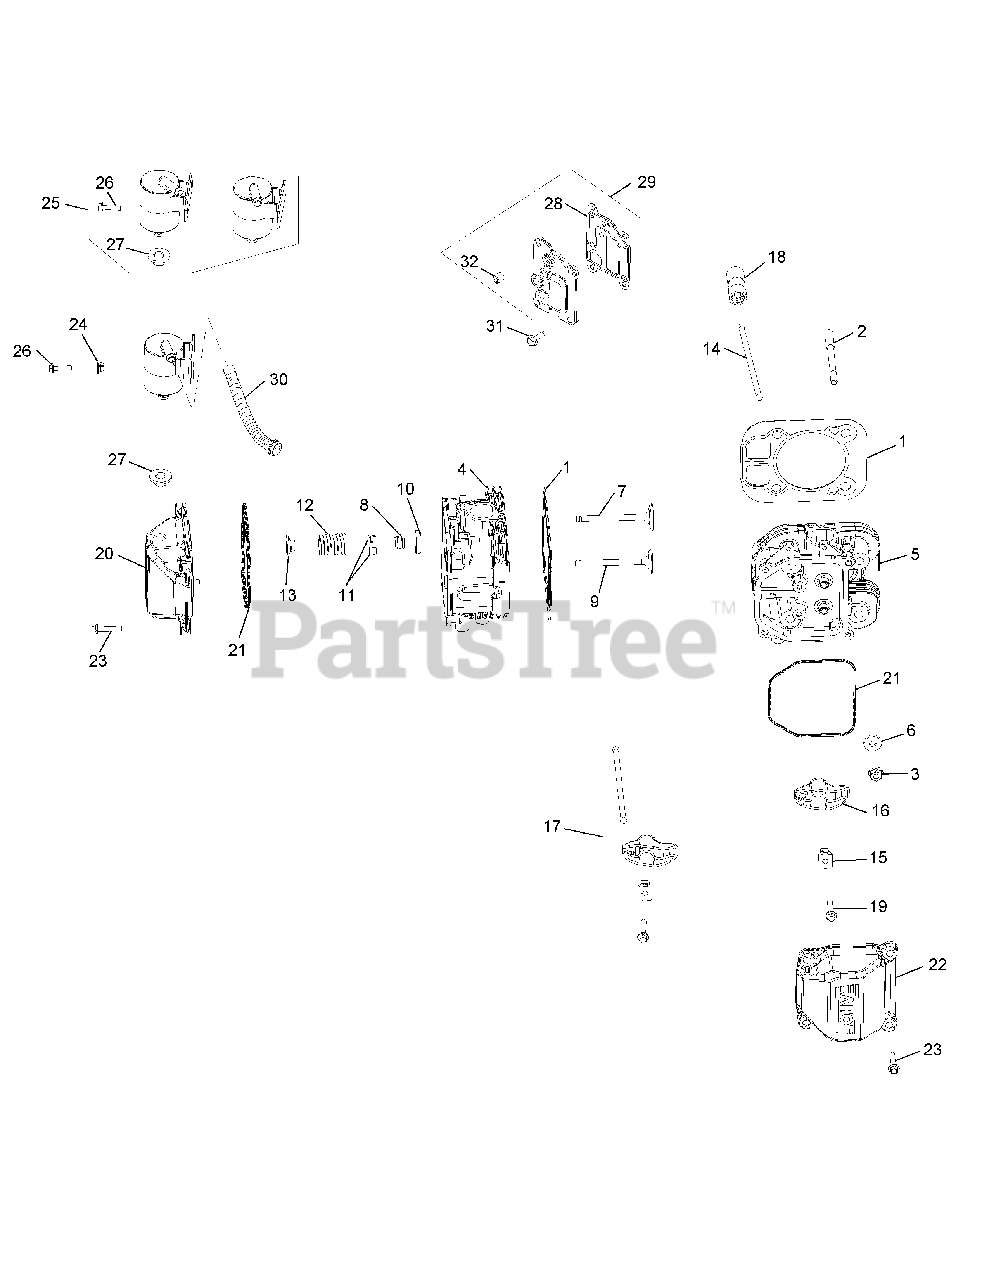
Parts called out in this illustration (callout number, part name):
1	Cylinder Head Gasket Kit
2	Stud, M8 x 1.25
3	Flange Nut, M8 x 1.25
4	#1 Cylinder Head Assembly Kit
5	#2 Cylinder Head Assembly Kit
6	Flat Washer, 8.6 mm
7	Intake Valve (STD)
7	Intake Valve (.25)
8	Valve Band Seal
9	Exhaust Valve (STD)
9	Exhaust Valve (.25)
10	Spring Retainer
11	Retainer Kit
12	Valve Spring
13	Valve Spring Cap
15	Rocker Arm Pivot
17	Valve Train Kit
18	Hydraulic Valve Lifter Kit
19	Flange Screw, M6 x 1.0 x 34
20	Valve Cover Kit
21	Valve Cover O-Ring
22	Plain Rocker Cover Kit
23	Flange Screw, M6 x 1.0 x 30
25	Breather Separator Kit (Inc. 26-27)
26	Hi-Lo Hex Flange Screw
27	Rubber Grommet
28	Breather Gasket
29	Breather Cover Kit w/ Gskt. (Inc. 28 & 32)
31	Flange Screw, M6 x 1.0 x 20
32	Pipe Plug, 1/8
